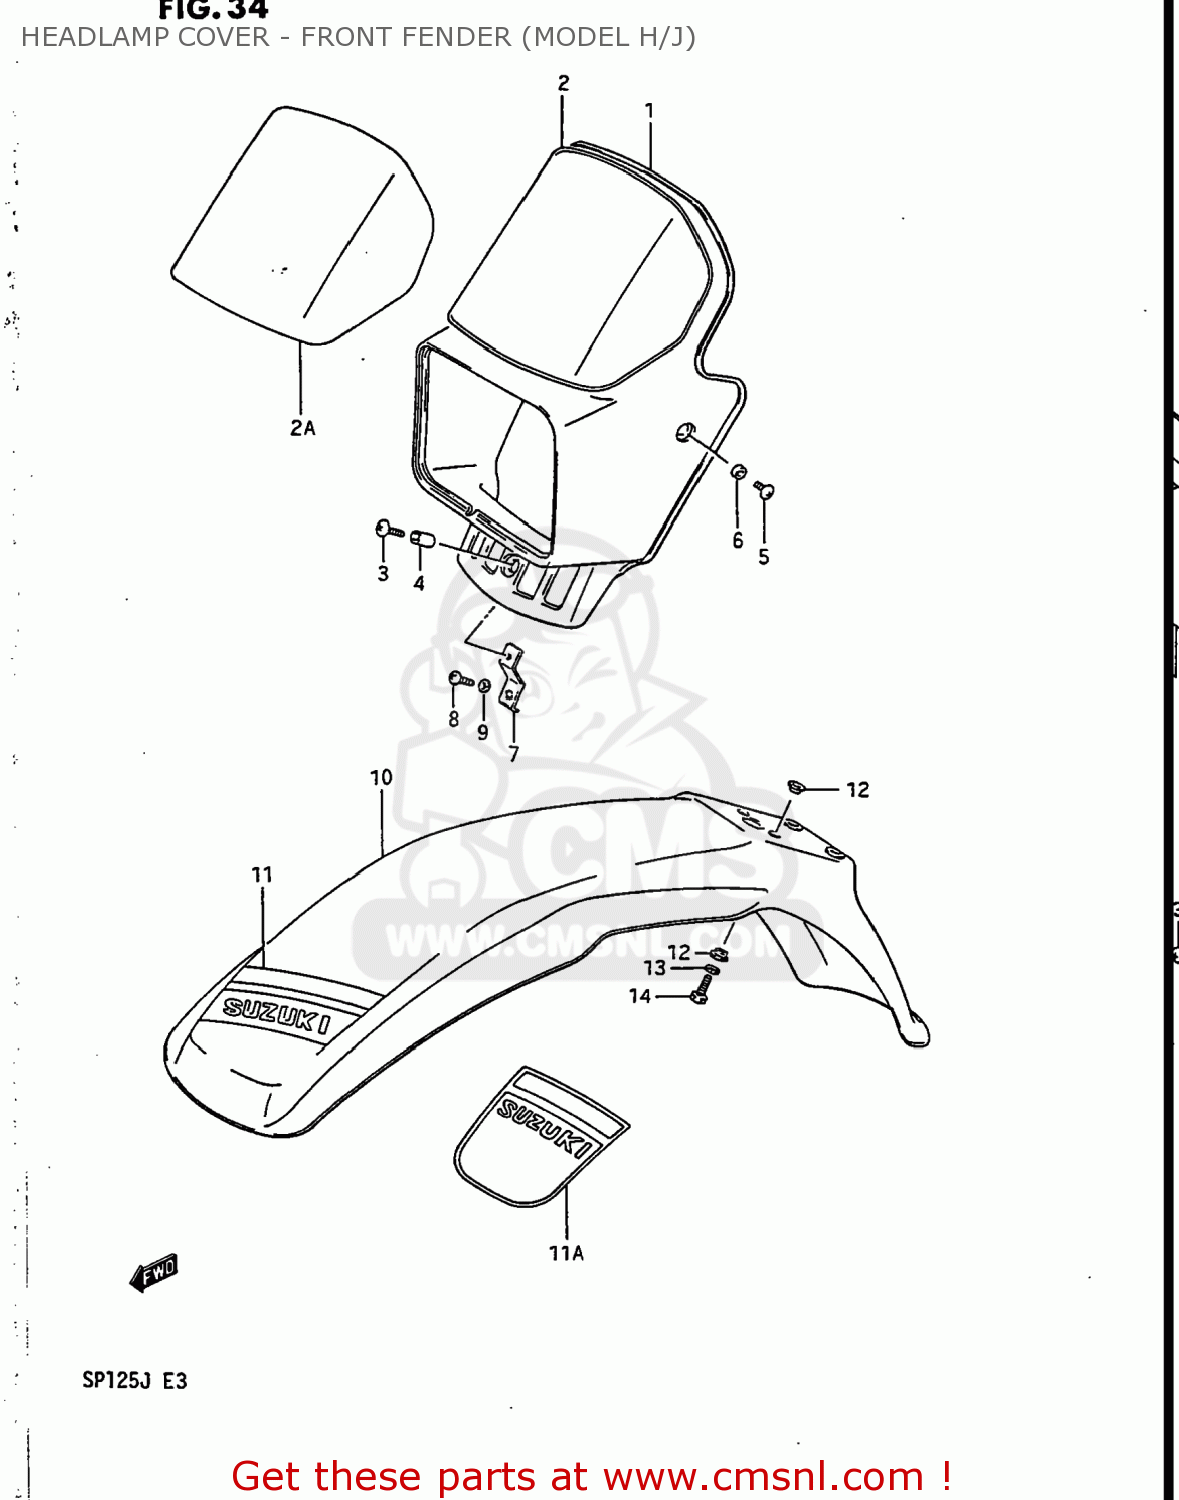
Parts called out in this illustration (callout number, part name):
1	COVER COMP,HEADLAMP
2	TAPE SET,HEADLAMP COVER
2A	TAPE SET,HEADLAMP COVER S
3	SCREW, CENTER
4	SPACER (6.1X8X12)
5	SCREW 6X12
6	SPACER (6.1X8X3.5)
7	BRACE,HEADLAMP HOUSING LWR
8	SCREW 6X12
9	WASHER,LOCK
10	FENDER,FRONT
11	TAPE SET,FRONT FENDER
11A	TAPE,FRONT FENDER
12	WASHER
13	WASHER,LOCK
14	BOLT
